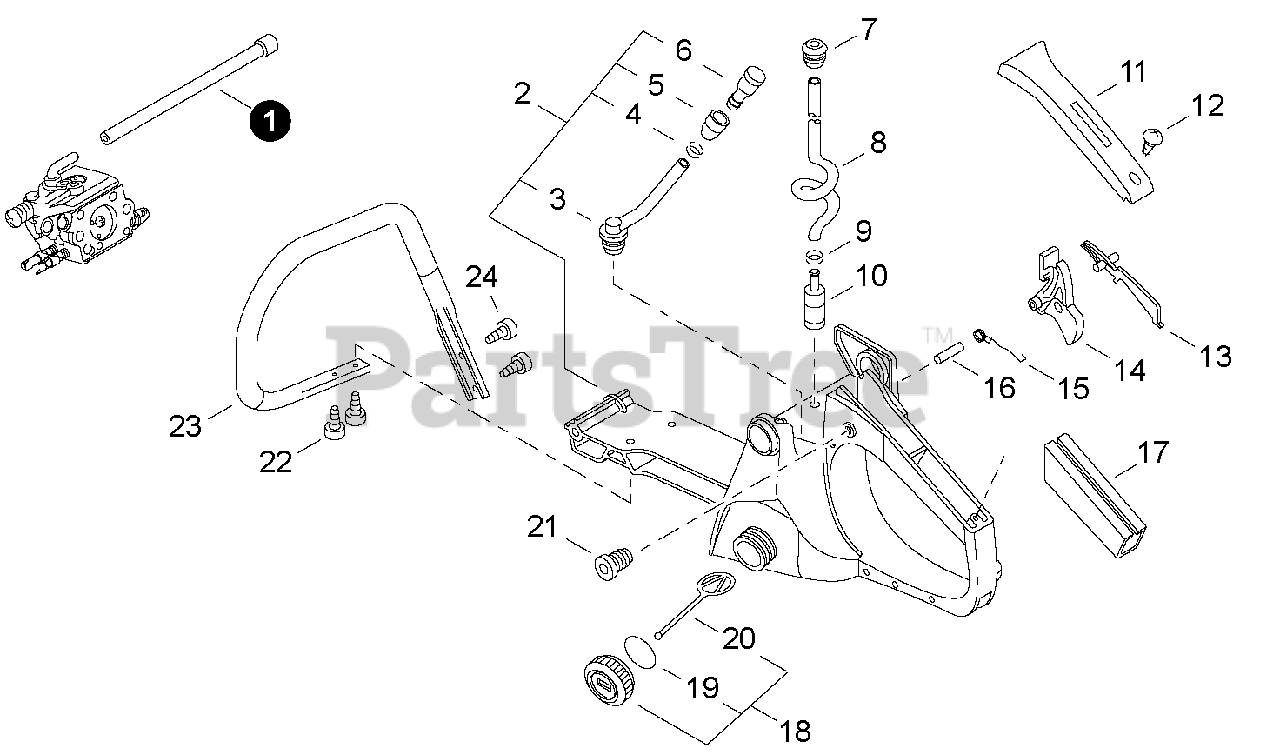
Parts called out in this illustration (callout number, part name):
1	PIPE - 3X6X105 -- BLACK
2	HANDLE ASSY - REAR
3	PIPE - VENT
4	CLIP - 6.5
5	COVER, VENT
6	VENT, FUEL TANK
8	PIPE - FUEL
9	CLIP - 6
10	FILTER, FUEL
11	COVER, HANDLE
12	SCREW - 4X14
13	LEVER, TRIGGER LOCKOUT
14	TRIGGER, THROTTLE
15	SPRING, TRIGGER
16	PIN - SPRING -- 4X30
17	GRIP, HANDLE
18	CAP ASSY - ORANGE
19	O-RING - 22
20	CONNECTOR, CAP
22	SCREW - 5X16
23	HANDLE - FRONT
24	SCREW - 5X20 -- TAPPING
